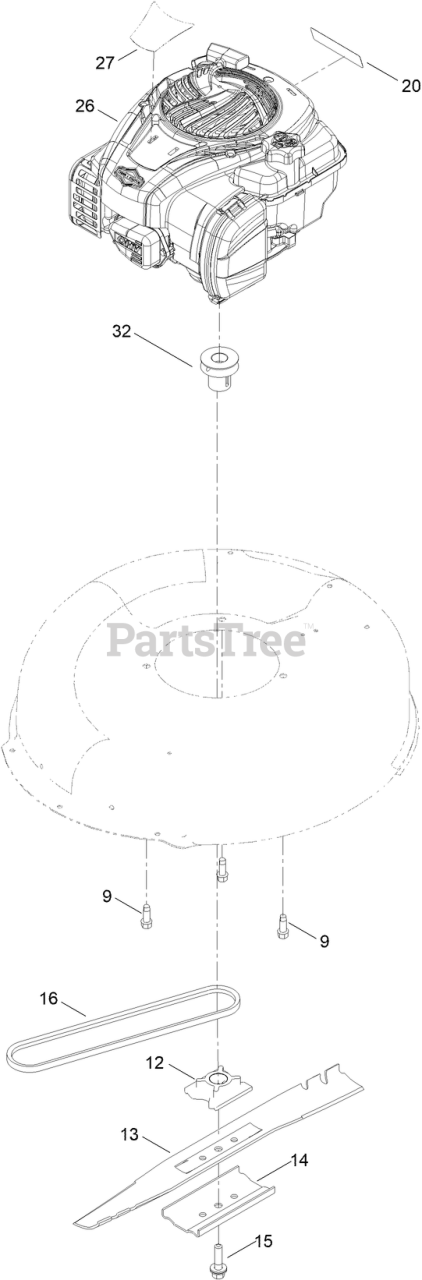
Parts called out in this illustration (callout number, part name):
9	SCREW-TAPTITE
12	RETAINER-BLADE
14	SUPPORT-BLADE
15	BOLT-BLADE
20	DECAL-ARRESTOR, SPARK
26	ENGINE-BRIGGS, 550 EX
27	DECAL-ENGINE
